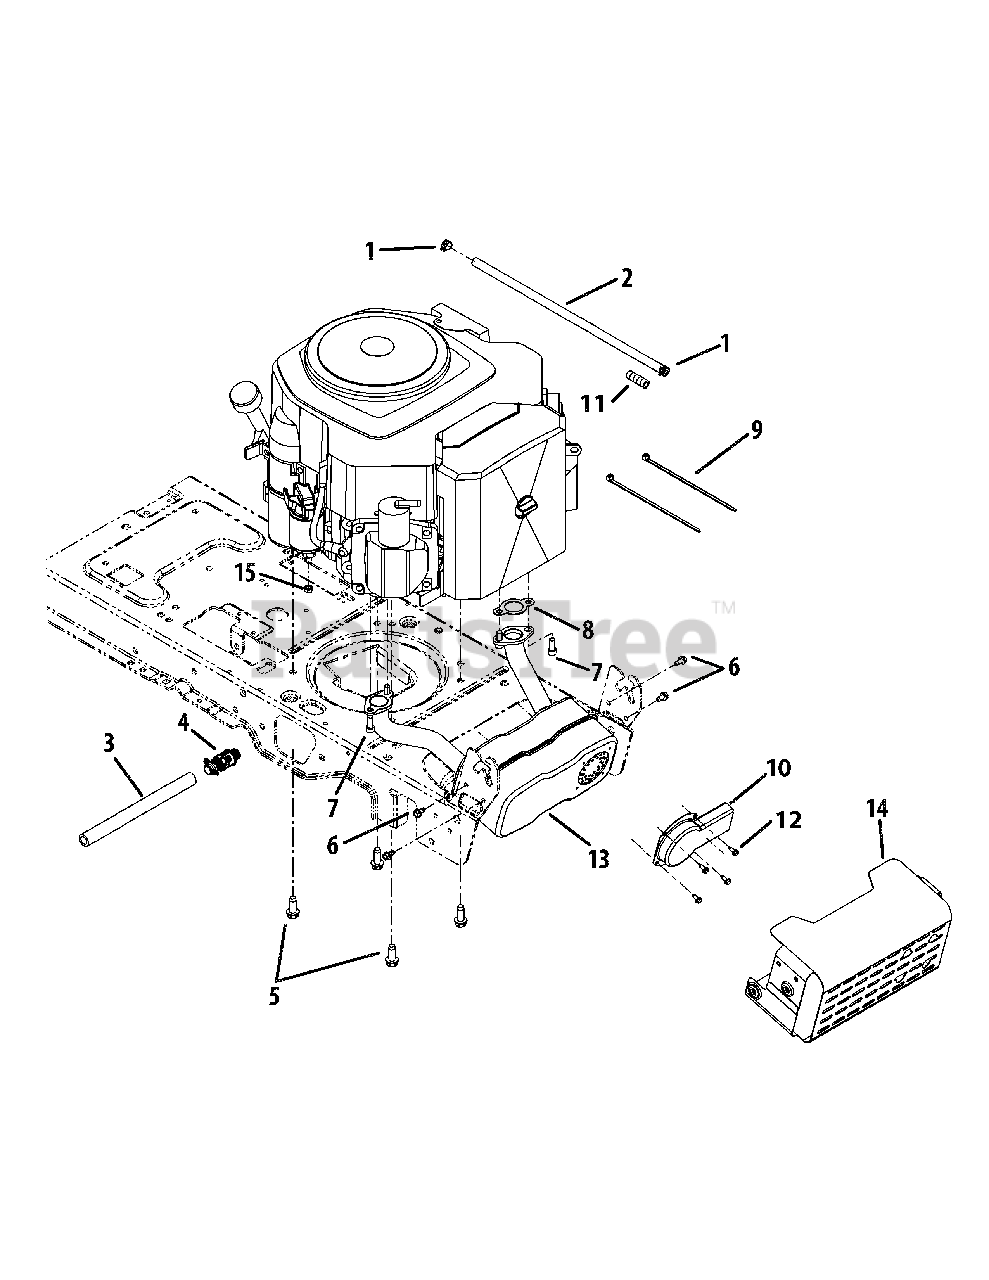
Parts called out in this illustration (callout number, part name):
1	Hose Clamp
2	Fuel Line
3	Oil Drain Hose
4	Oil Drain
5	TT Screw 3/8-16 x 1.00
6	Hex Wash S-Tapp Screw 1/4-20 x .50
7	Screw. 5/16-18 x .75
8	Exhaust Gasket
9	Cable Tie
10	Long Muffler Deflector
11	Vent Hose
12	Hex AB Screw #8-18 x .50
13	Muffler
14	Muffler Shield Assembly
15	Sems Nut 1/4-20
